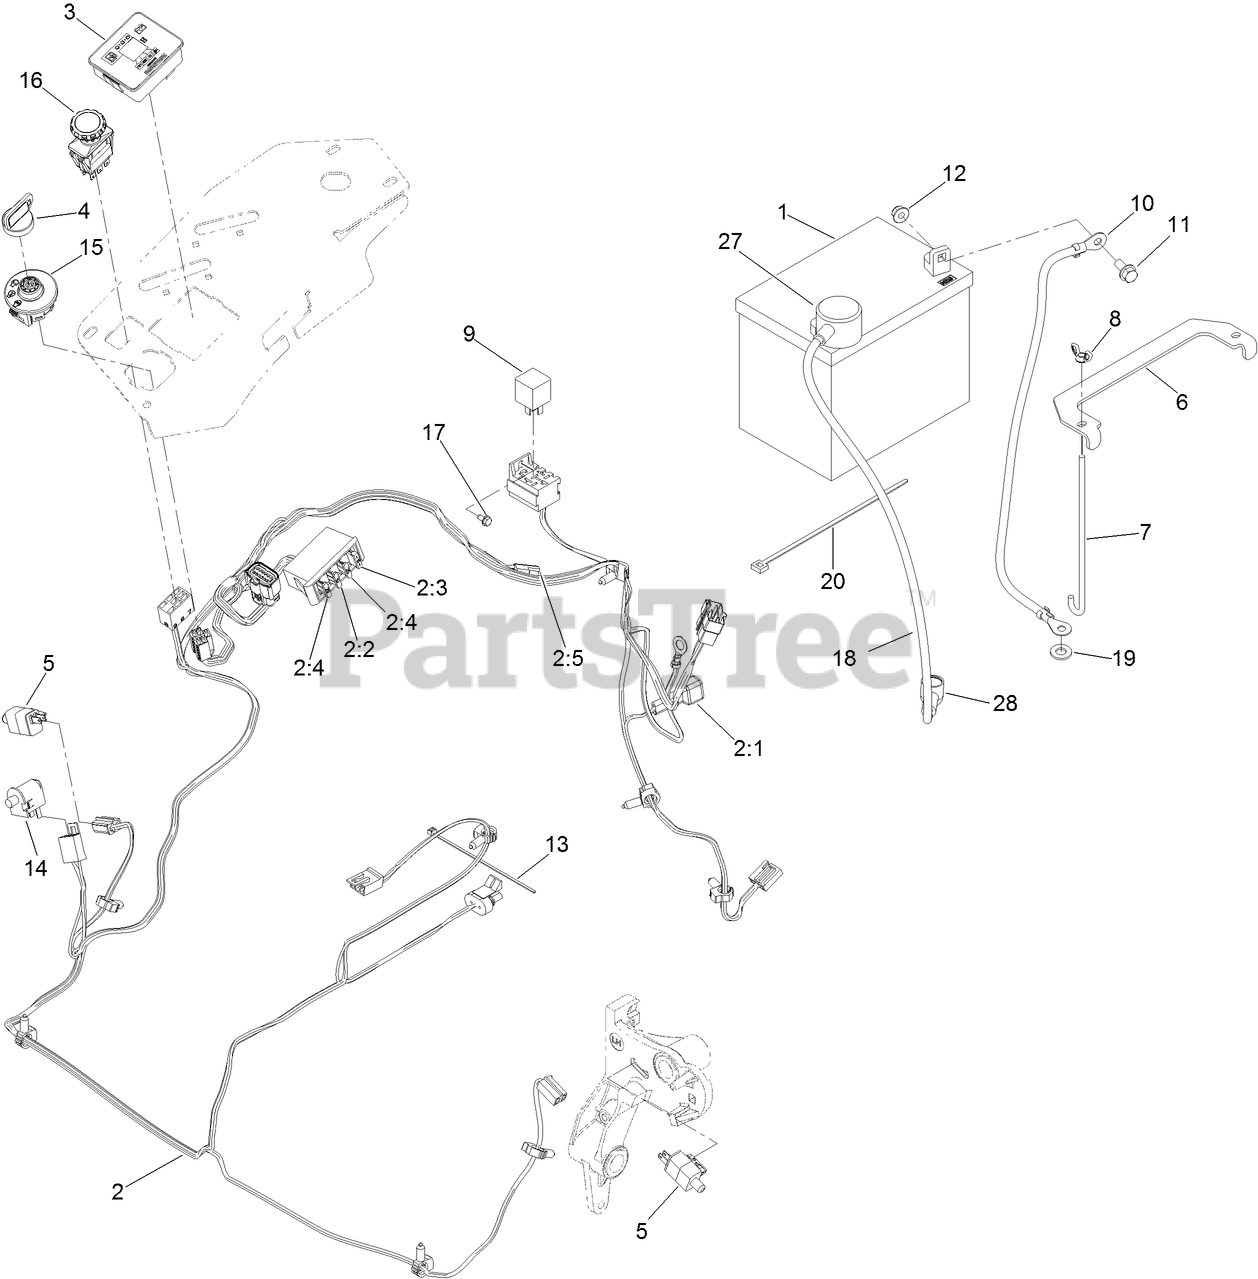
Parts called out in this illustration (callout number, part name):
1	BATTERY-DRY
2	HARNESS-WIRE, MAIN
2:2	FUSE-BLADE, 10 AMP
2:3	FUSE-BLADE, 15 AMP
2:4	FUSE-BLADE, 25 AMP
2:5	CAP-PLUG
3	FUEL/HOUR METER ASM
4	KEY-IGNITION
5	SWITCH
6	STRAP-TIE DOWN, BATTERY
7	BOLT-HOLDDOWN
8	WINGNUT
10	CABLE-BATTERY, NEGATIVE
11	SCREW-HHF
12	NUT-HF, NI
13	TIE-CABLE
14	SWITCH-BAIL
15	SWITCH-IGNITION
16	SWITCH-PTO, 10 AMP
17	SCREW-HWH
18	CABLE-BATTERY, POSITIVE
19	WASHER-FLAT
20	TIE-PLASTIC
27	INSULATOR-BATTERY
28	INSULATOR-SOLENOID
